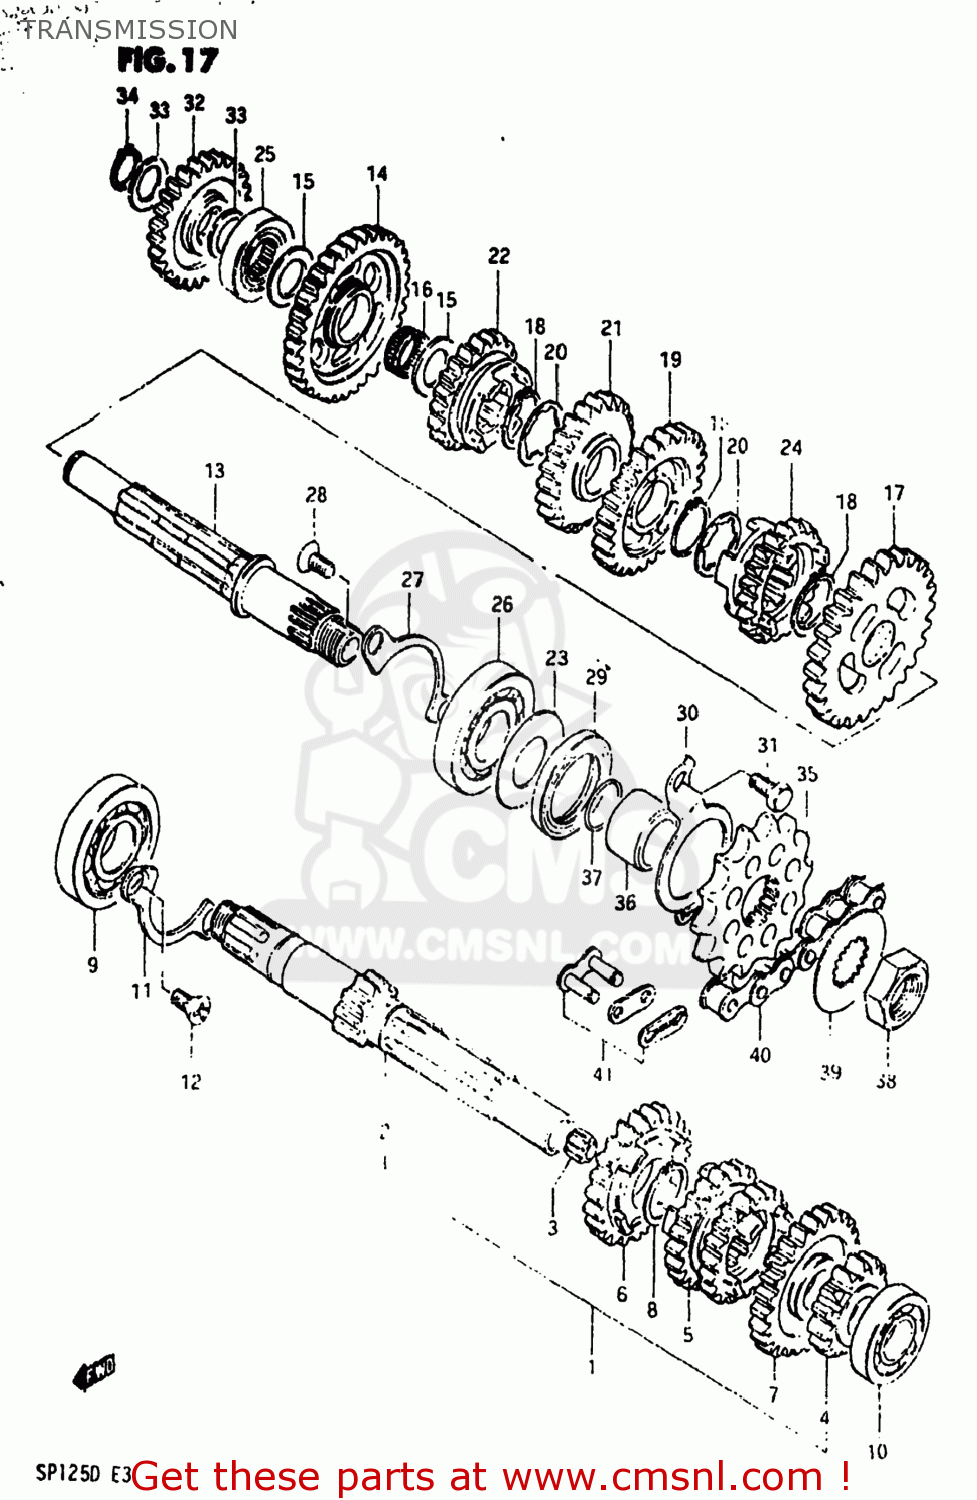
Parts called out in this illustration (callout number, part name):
1	SHAFT,COUNTER
2	SHAFT,COUNTER
3	BUSHING
4	GEAR,SECOND DRIVE
5	GEAR,THIRD & FOURTH DRIVE,N
6	GEAR,FIFTH DRIVE
7	GEAR,SIXTH DRIVE
8	CIRCLIP
9	BEARING
10	BEARING, LH
11	RETAINER,DRIVE SHAFT BEARING
12	SCREW
13	SHAFT,DRIVE
14	GEAR,FIRST DRIVEN
15	WASHER
16	BEARING(15X19X7.8)
17	GEAR,SECOND DRIVEN
18	CIRCLIP
19	GEAR,THIRD DRIVEN
20	WASHER,LOCK
21	GEAR,FOURTH DRIVEN
22	GEAR,FIFTH DRIVEN
23	WASHER,OIL SEALING
24	GEAR,SIXTH DRIVEN
25	BEARING(15X33X12)
26	Bearing
27	RETAINER,DRIVE SHAFT BEARING
28	SCREW
29	SEAL,OIL(27X40X6)
30	PLATE,DRIVESHAFT OIL
31	BOLT
32	GEAR,KICK STARTER IDLE
33	WASHER
34	CIRCLIP,15MM
35	SPROCKET,ENGINE
36	SPACER
37	O RING(D:2.4,ID:19)
38	NUT
39	WASHER,LOCK
40	CHAIN ASSEMBLY,DRIVE
41	JOINT SET,CHAIN
